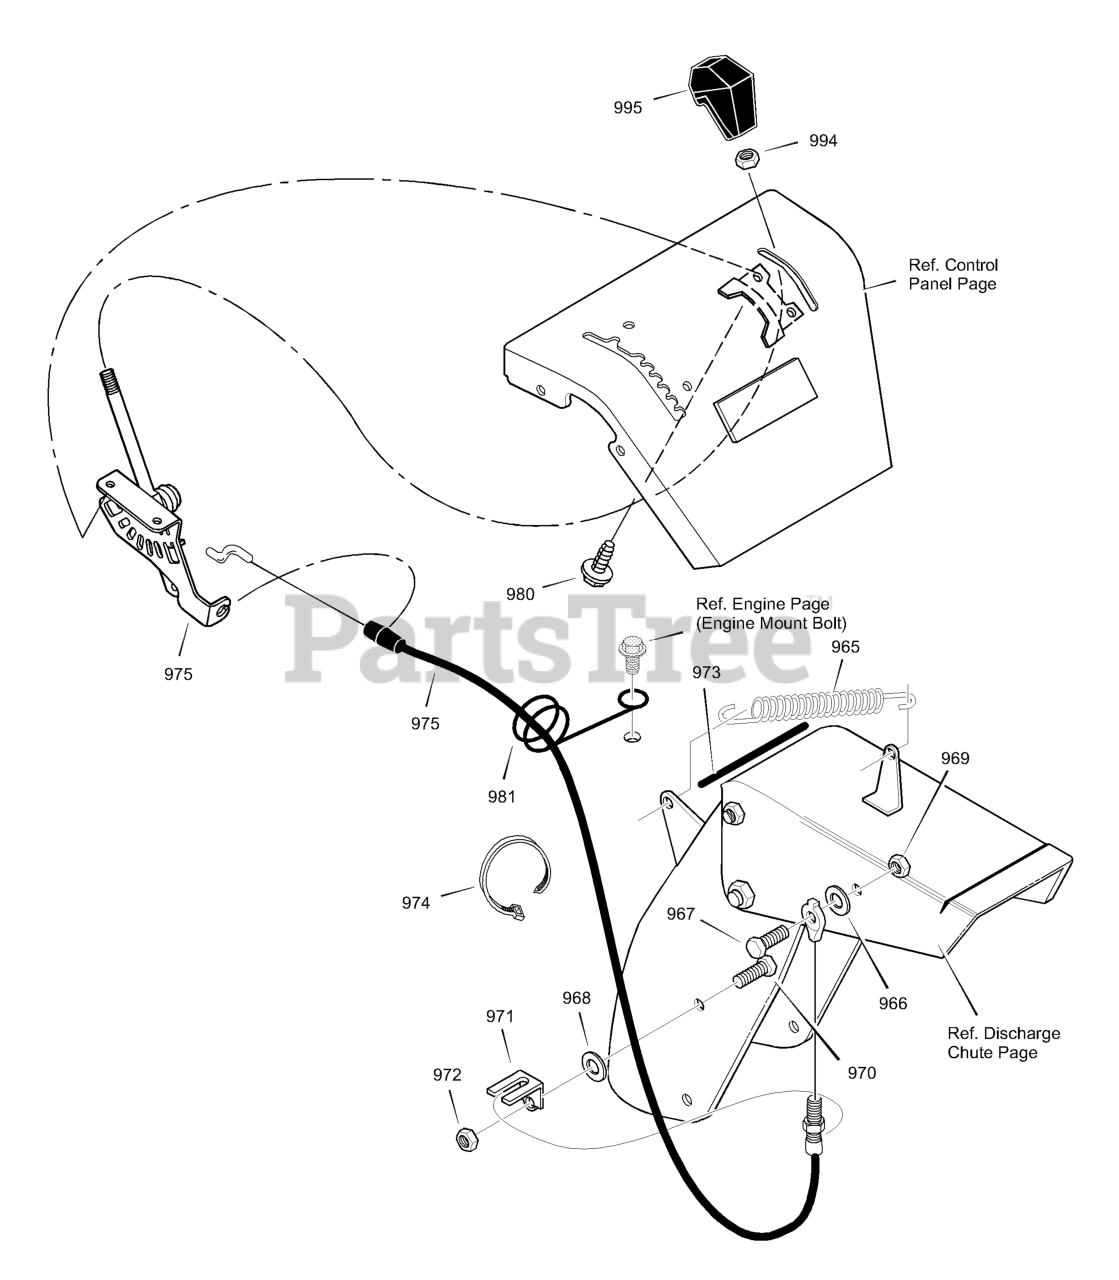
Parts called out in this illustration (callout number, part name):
965	TENSION SPRING
966	FLATWASHER
968	FLATWASHER
970	SCREW 5/16-18 X .75
971	BRACKET, CABLE CHUTE
972	NUT
973	TRIM STRIP, GREY
974	TIE, CABLE
975	ASSY, CHUTE DEF. CONTROL
980	SCREW
981	WIRE FORM, REMOTE CHUTE CABLE
995	KNOB, SHIFT (GREY)
